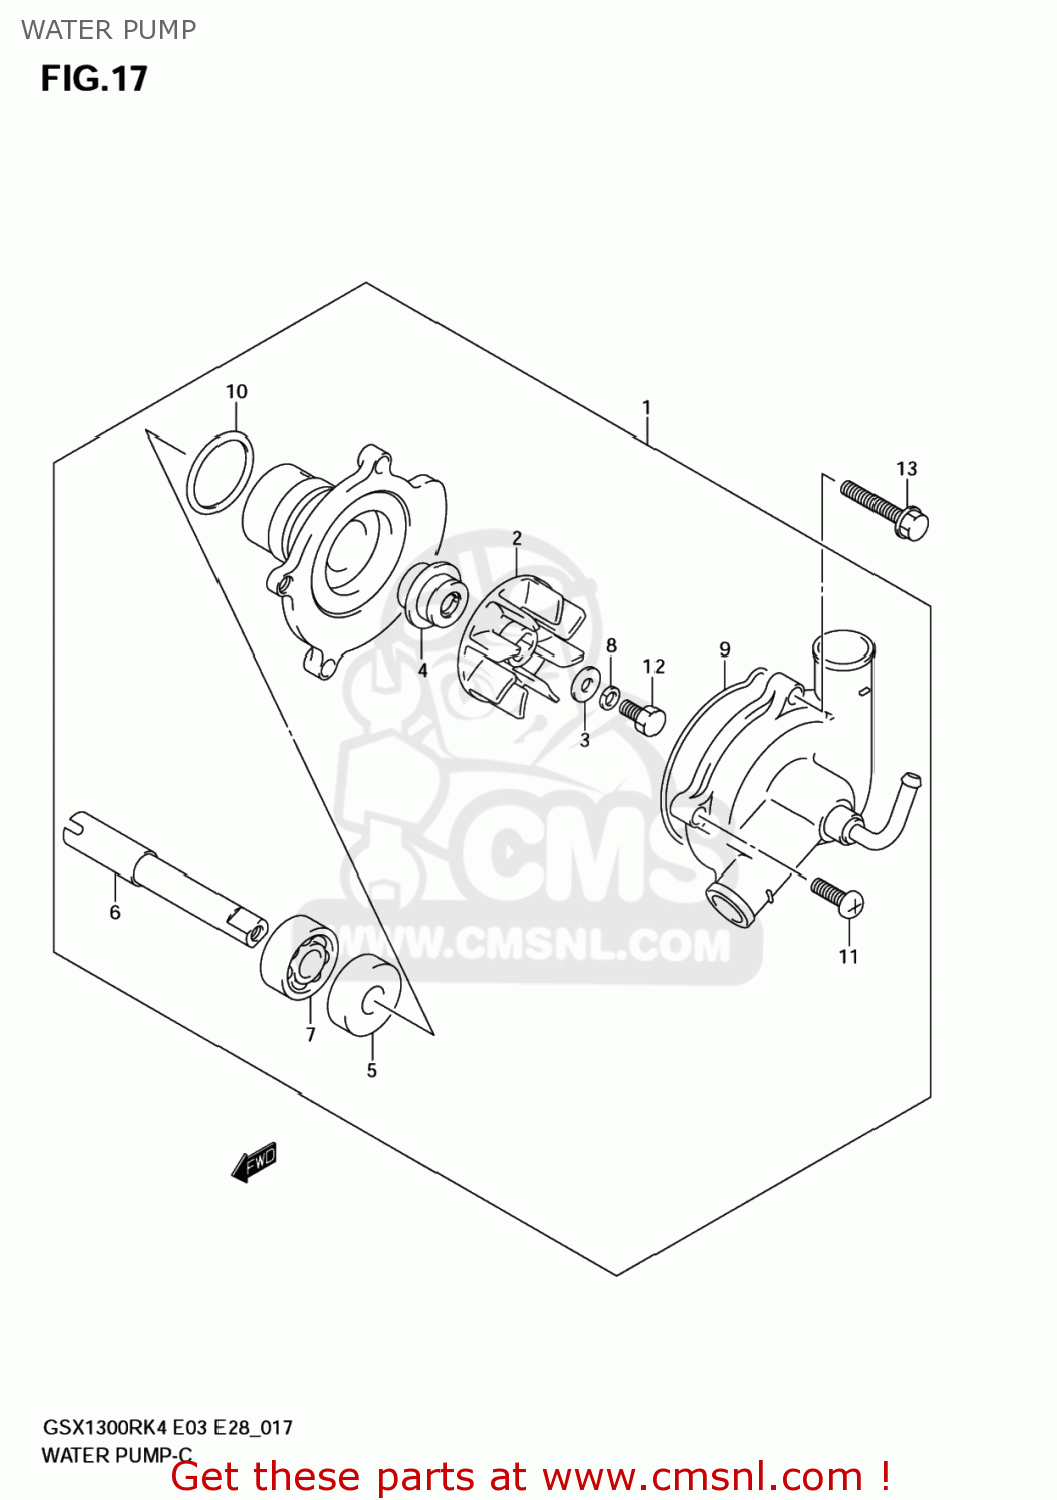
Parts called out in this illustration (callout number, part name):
1	PUMP ASSEMBLY,WATER
2	IMPELLER
3	GASKET(6X15X2.2) (NAS)
4	SEAL,MECHANICAL
5	SEAL,OIL(10X21X5)
6	SHAFT
7	BEARING(10X26X8)
8	WASHER
9	O RING
10	O RING,WATER PUMP HOLDER
11	SCREW 6X16
12	BOLT(6X13)
13	BOLT
